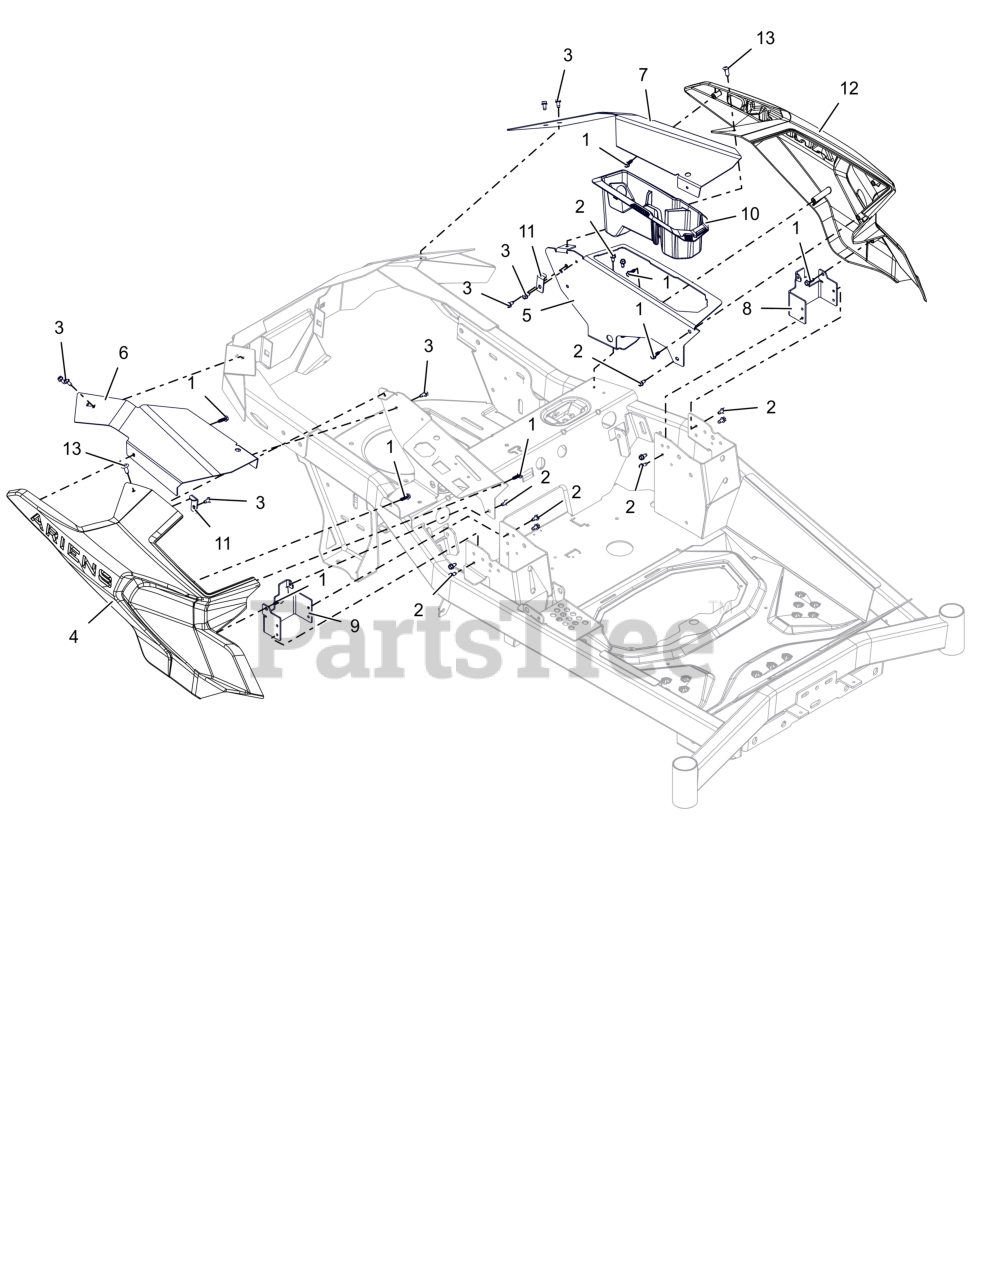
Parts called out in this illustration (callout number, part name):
1	SCR, PLASTITE .25-10X.75 ZCC
2	SCR-TAP .25-20X.50 HWH ZCC
3	SCR-TAP .25X.50 HWH ZB500
4	FENDER-RH-ARIENS
5	PANEL- CONTROL-LH-ARIENS
6	BRKT- REAR FENDER MOUNT-A-RH
7	BRKT-REAR FENDER MOUNT-A-LH
8	BRKT-FRONT FENDER MOUNT-A-RH
9	BRKT-FRONT FENDER MOUNT-A-LH
10	HOLDER- CUP - IKON
11	PLATE, FENDER HOLDDOWN (ORANGE)
12	KIT,LH ARIENS FENDER W/ DECAL
13	XMAS TREE FASTNER-BLACK
